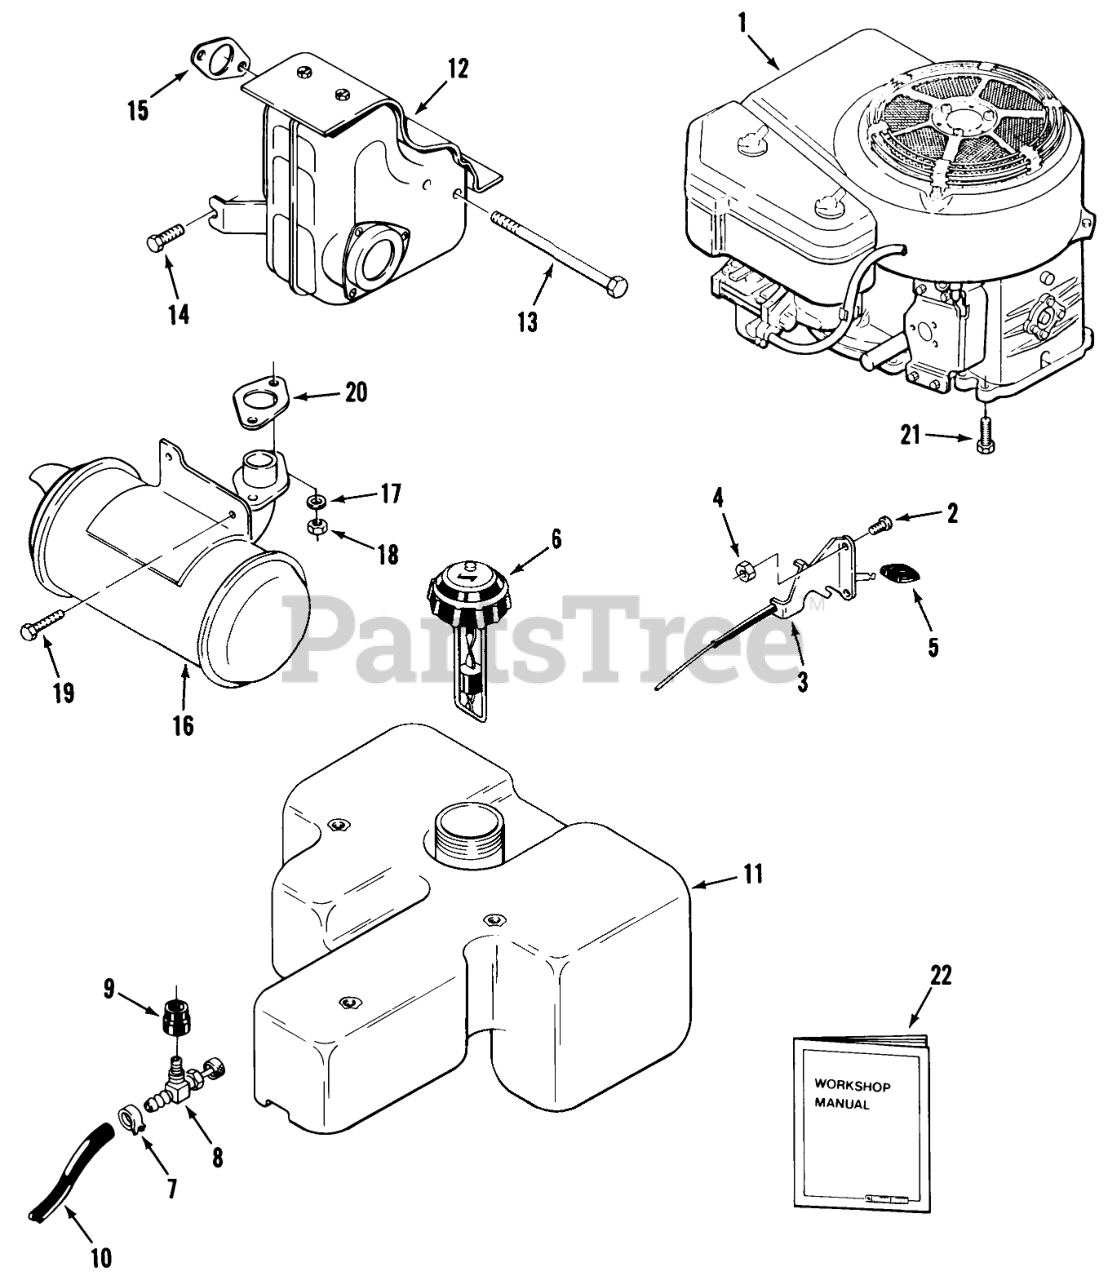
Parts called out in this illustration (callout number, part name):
1	Engine-12.5 HP-Kawasaki Model FB460V, Type BS-26 252-H
1	Engine-17 HP-Kawasaki Model FC540V, Type AS-08 257-H
2	Screw
3	THROTTLE-CONTROL
4	Nut
5	KNOB-THROTTLE
6	ASS'Y-GAUGE CAP
7	Clamp
8	VALVE-FUEL
9	BUSHING
10	Fuel Hose 54 in. (137.2 cm)
11	Fuel Tank
12	MUFFLER-FB-460V
14	BOLT-FLANGED
15	GASKET-L MUFFLER
16	Muffler 257-H
17	Lockwasher
18	Nut M8x1.25 257-H
19	HHCS M8X1.25X15
20	OBS GASKET-EXH FC-540V
21	BOLT-FLANGED
